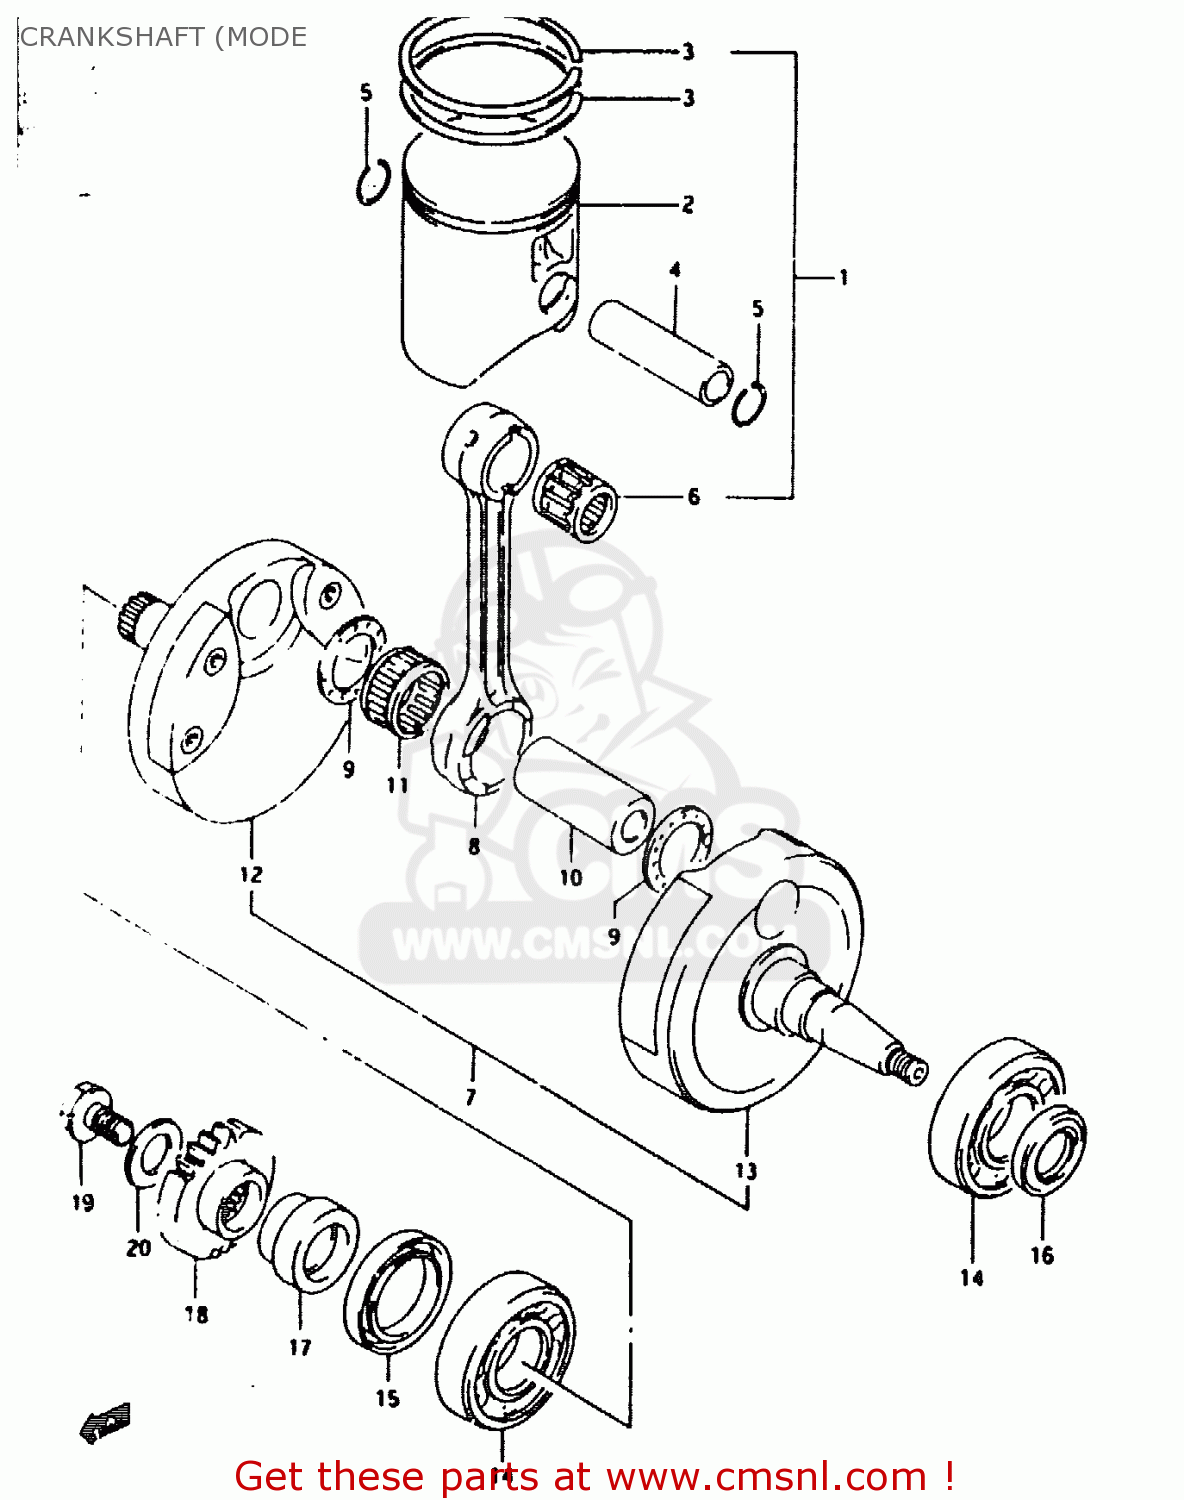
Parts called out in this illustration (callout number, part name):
1	PISTON KIT
2	PISTON
3	RING, PISTON
4	PIN,PISTON
5	CIRCLIP,PISTON PIN
6	BEARING(18X23X22)
7	CRANKSHAFT ASSEMBLY
8	ROD,CONNECTING
9	WASHER(24X38.5X1.5)
10	PIN,CRANK
11	BEARING(24X30X20)
12	CRANKSHAFT,R
13	CRANKSHAFT COMP,LEFT
14	BEARING
15	SEAL,OIL(38X52X8)
16	SEAL,OIL(25X37X6)
17	SPACER,PRIMARY DRIVE GEAR
18	GEAR,PRIMARY DRIVE (NT:
19	O RING(D:2.4,ID:21.8)
20	WASHER
21	BOLT,PRIMARY DRIVE GEAR
22	WASHER
